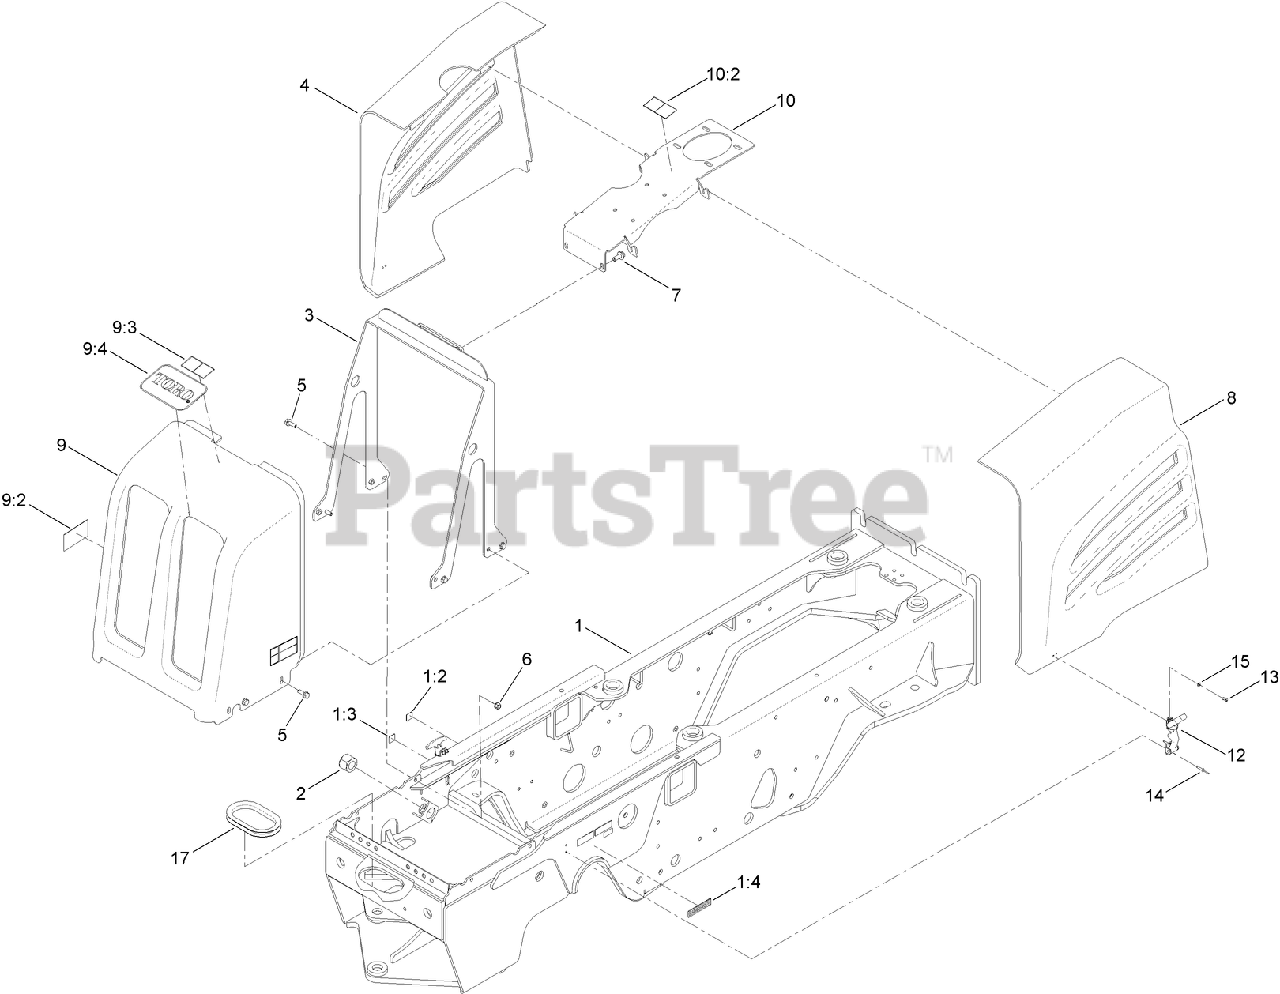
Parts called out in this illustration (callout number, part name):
1	CHASSIS FRAME ASM
1:2	DECAL-FLUID, HYDRAULIC (OUT)
1:3	DECAL-FLUID, HYDRAULIC (IN)
1:4	DECAL-ARRESTER, SPARK
3	SUPPORT-HOOD
4	HOOD-RH
5	SCREW-HHF
6	NUT-LOCK, NI
7	SCREW-HHF
8	HOOD-LH
9	NOSE CLIP ASM
9:2	DECAL-WARNING, FAN
9:3	DECAL-WARNING, RADIATOR
9:4	DECAL
10	HOOD SUPPORT ASM
10:2	DECAL-SURFACE, HOT
12	LATCH-DRAW, FLEXIBLE
13	RIVET-POP
14	RIVET-BLIND
15	WASHER-PLAIN
17	TRIM-EDGE
